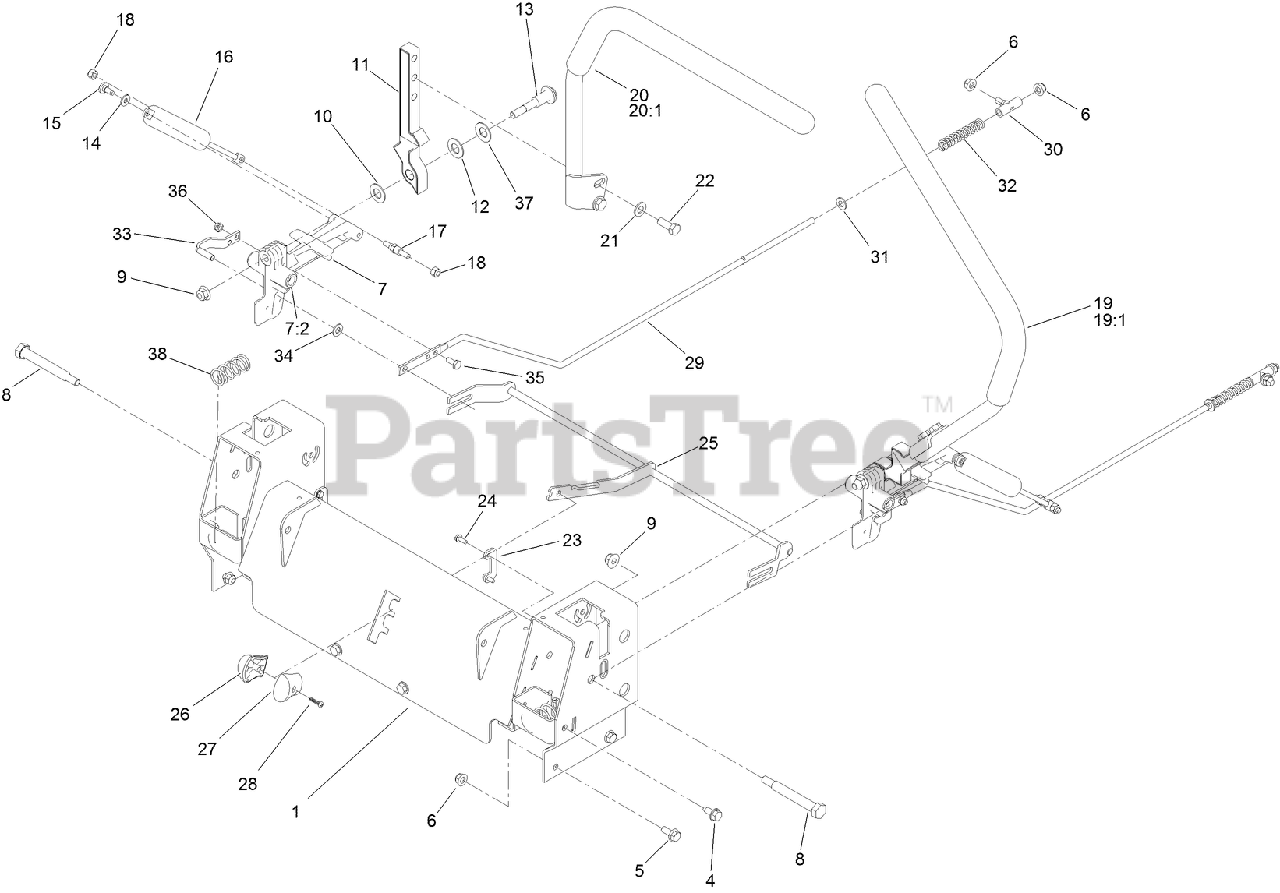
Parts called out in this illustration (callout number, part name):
1	CONTROL BOX ASM
4	SCREW-HWHTF
5	SCREW-HHF
6	NUT-HF, NI
7	ACTUATOR ARM ASM
7:2	BUSHING-FLANGE
8	BOLT-PIVOT
9	NUT-HF, NI
10	WASHER-NYLON
11	ARM-CONTROL
12	WASHER
13	BOLT-PIVOT
14	WASHER
15	SCREW-SHOULDER
16	DAMPER
17	STUD-DAMPER
18	NUT-LOCK, NI
19	HANDLE-CONTROL, LH
20	HANDLE-CONTROL, RH
21	WASHER-FLAT
22	SCREW-HH
23	RETAINER
24	SCREW-TAPTITE
25	SPEED CONTROL ASM
26	KNOB-RH
27	KNOB-LH
28	SCREW-PPH
29	ROD-HYDRO
30	MOUNT-ROD, HYDRO
31	WASHER-PLAIN
32	SPRING-RETURN, NEUTRAL
33	PIN-ROD, HYDRO
34	SPACER-NYLON
35	SCREW-HH
36	NUT-LOCK, NI
37	WASHER-BELLEVILLE
38	SPRING-RETURN
